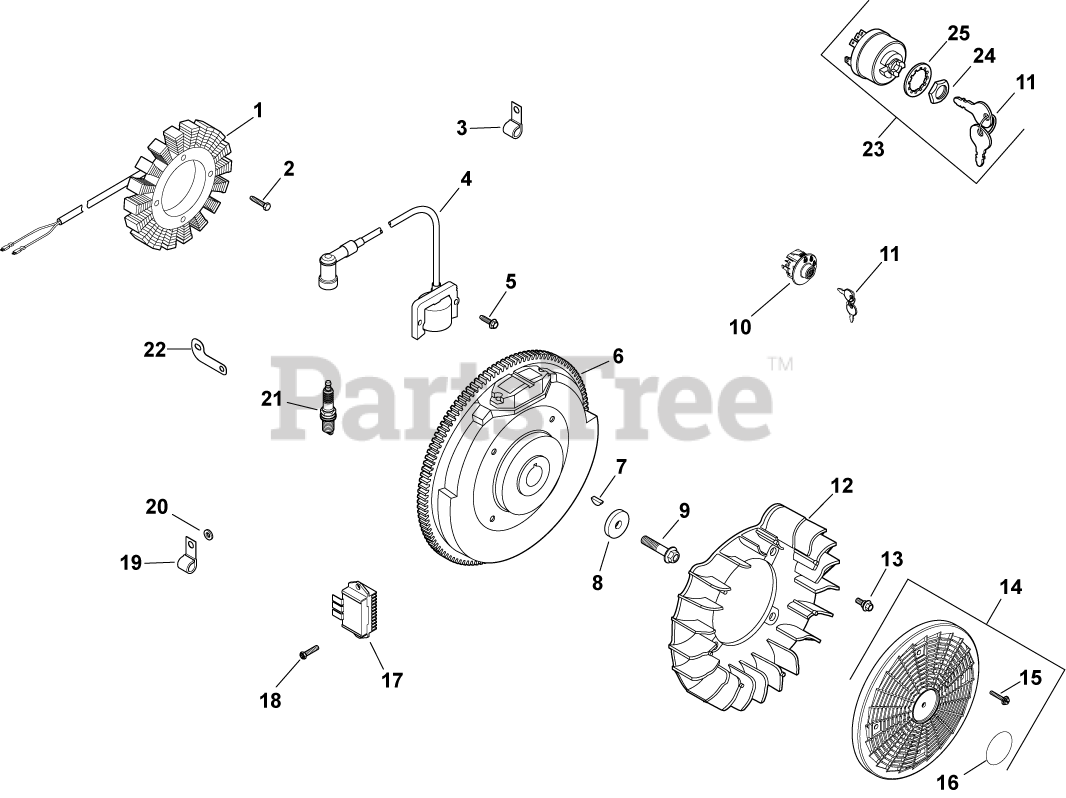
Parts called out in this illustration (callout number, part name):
1	KIT, 15 / 20 AMP STATOR
2	SCREW, M5X0.8X25 - (#25086402S)
4	MODULE, IGNITION
5	SCREW, FLG THD FRM M5X.8X20-(#25086399S)
6	FLYWHEEL ASSEMBLY (LW)
7	KEY, 3/16" X 5/8"
8	WASHER, FLAT 13/32"
9	SCREW, FLG M10X1.5X45 - (#25086361S)
10	KIT, KEY SWITCH (SNAP-IN)
11	KEY, SET -USE 48 340 01-S
12	FAN USE 24 755 253-S
13	BOLT, SHOULDER
14	KIT, GRASS SCREEN
15	SCREW, FLG SEMS M4X.7X25
16	DECAL, GRASS SCREEN USE 24 113 499-S
17	REG/RECTIFIER (20/25 AMP)-USE 25 403 20-
18	SCREW, HEX FLANGE HI-LO
19	CLIP, CABLE
20	WASHER, FLAT 1/4" (O.D. 1/2")
21	PLUG, SPARK (PRO SERIES)
22	BRACKET, GROUND STRAP USE 24 518 12-S
23	SWITCH ASSY, KEY (KM)-USE 25 099 32-S
24	NUT, KEY SWITCH
25	WASHER, INTERNAL TOOTH
2458452-S	MODULE, SPARK ADV -USE 24 584 89-S
